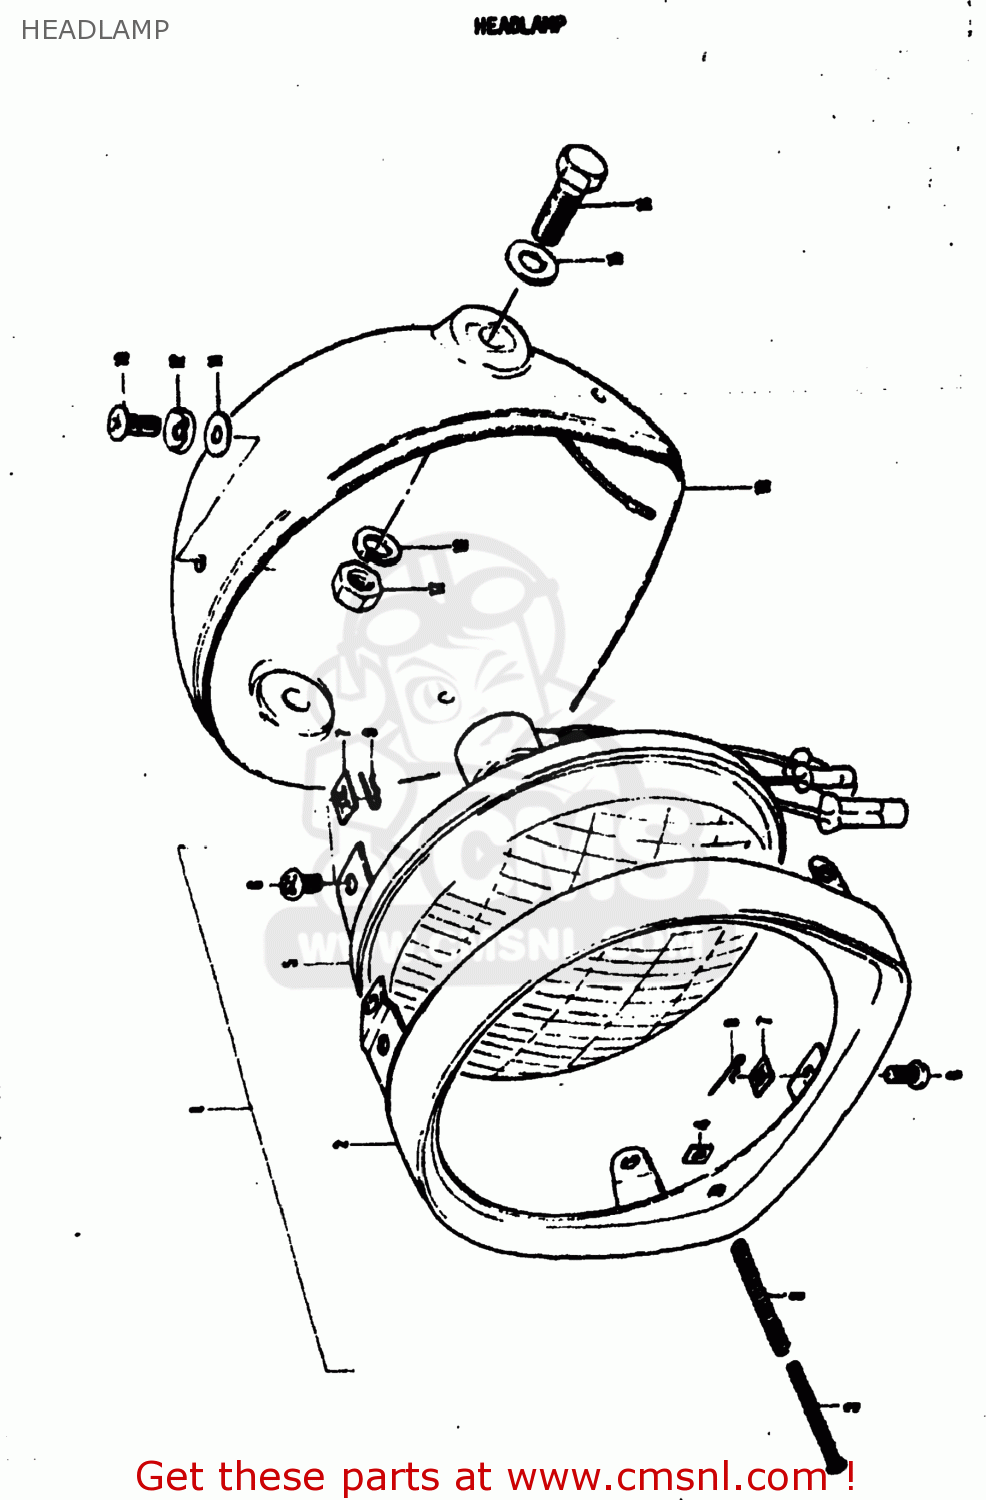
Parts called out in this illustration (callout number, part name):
1	RIM,HEADLAMP
2	SCREW,HEADLAMP ADJUST
3	NUT,HEADLAMP ADJUSTER
4	LAMP UNIT
5	SCREW,LENS
6	NUT,ADJUSTING
7	SPRING,HEADLAMP ADJUST
8	SOCKET,BULB
9	BULB
